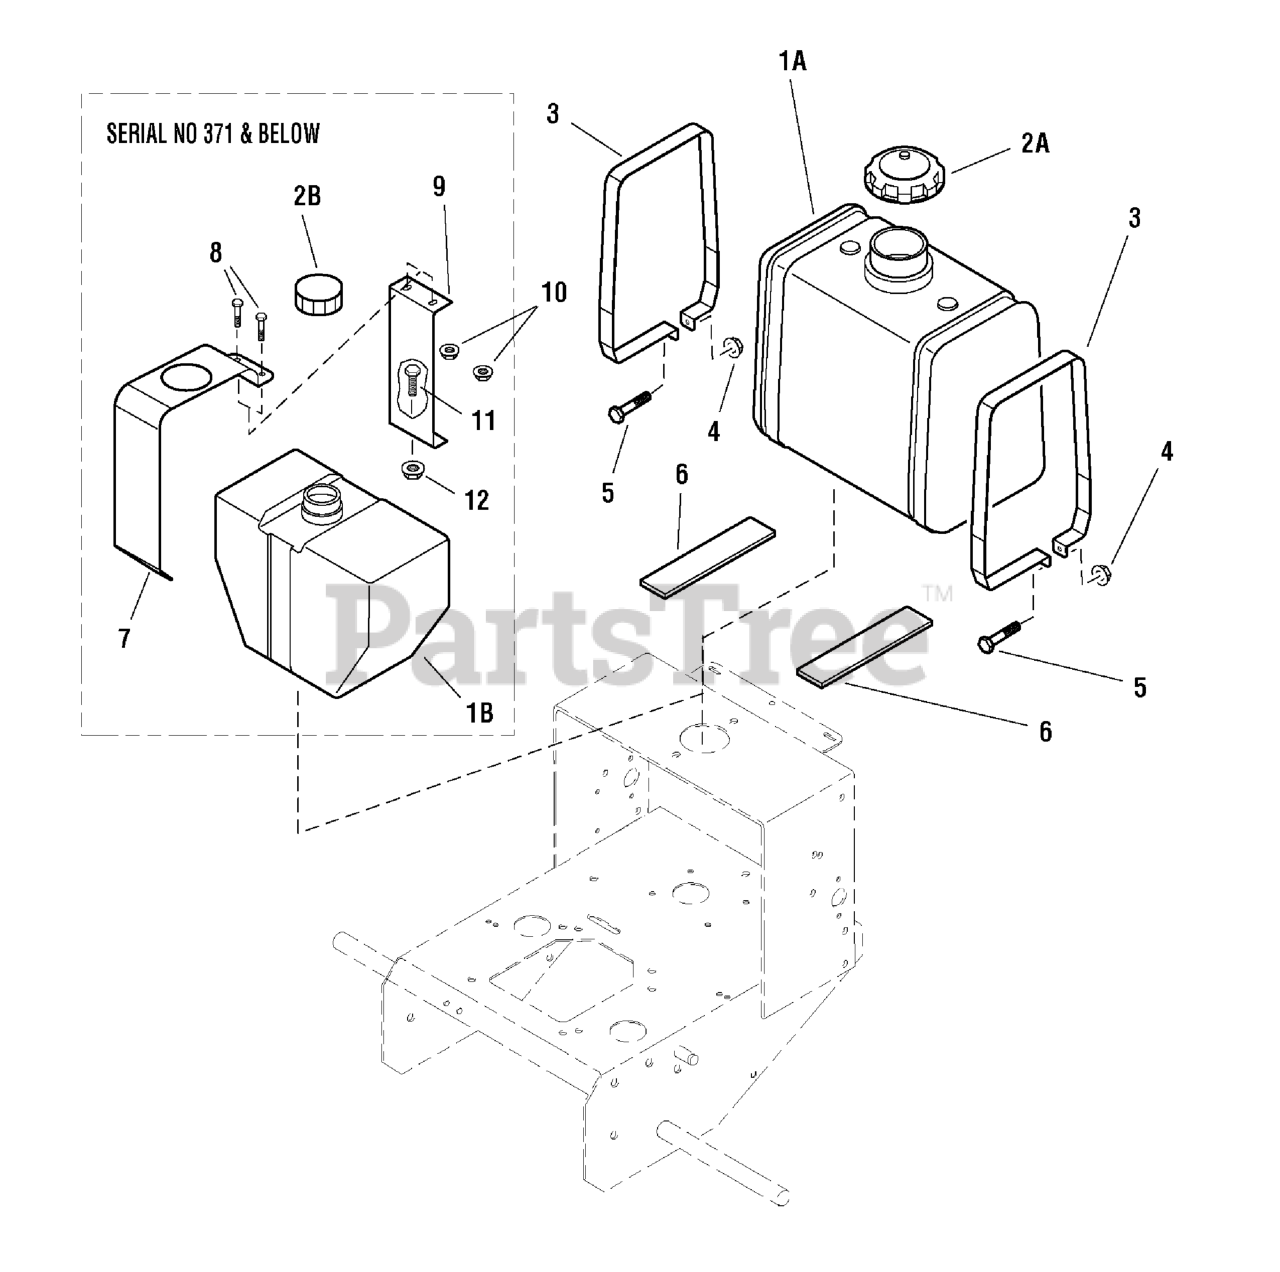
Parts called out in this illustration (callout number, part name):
1A	TANK, FUEL, PLASTIC, 5 GALLON W/ FUEL LINE
1B	FUEL TANK, 4 Gallon
2A	CAP, GASOLINE, VENTED
2B	CAP, Fuel Tank
3	FUEL TANK STRAP
4	NUT, 1/4-20 HEX SERR. FLANGE
5	BOLT, 1/4-20 X 2", GD5
6	RUBBER PAD
7	FUEL TANK STRAP
8	BOLT, 5/16-18 X 1 GD5 YZ
9	FUEL TANK HOLD DOWN
10	NUT, 5/16-18 HEX SERRATED FLANGE (LARGE)
11	BOLT, 5/16-18 X 3/4 GD5
12	NUT, 3/8-16 Hex Serrated Flange
